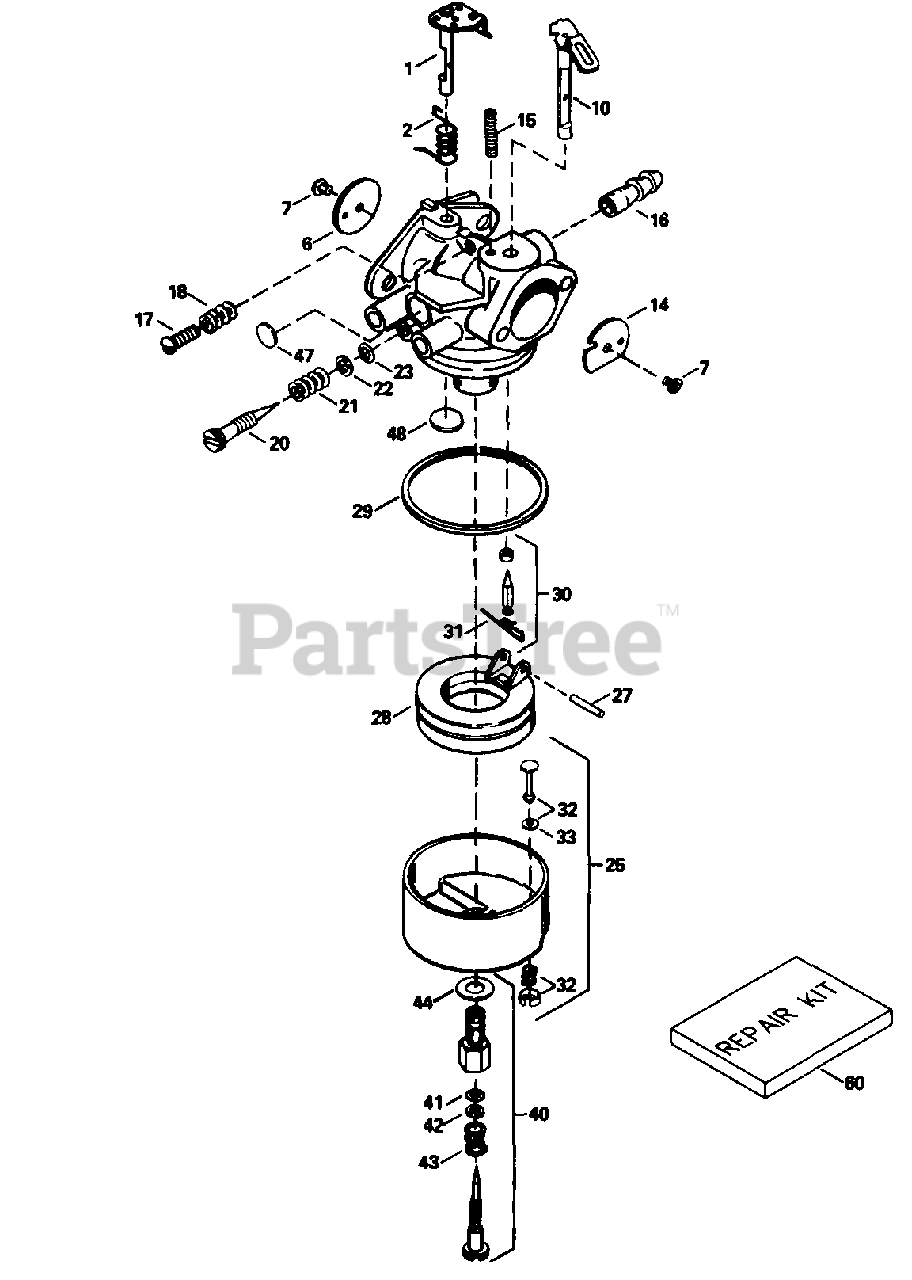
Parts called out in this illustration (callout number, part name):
1	Throttle Shaft and Lever Ass'y.
2	Throttle Return Spring
6	Throttle Shutter
7	Throttle & Choke Shutter Screw
10	Choke Shaft & Lever Ass'y
14	Choke Shutter
15	Choke Positioning Spring
16	Fuel Fitting
17	Idle Speed Screw
18	Tension Spring
20	Idle Mixture Screw
21	Spring, Idle Mixture Screw
22	Washer, Idle Screw
23	"O"-Ring, Idle Screw
25	Float Bowl
27	Shaft, Float
28	Float
29	"O"-Ring, Float Bowl to Body
30	Inlet Needle, Seat & Spring Clip
31	Spring Clip
32	Bowl Drain Ass'y.
33	Drain Plunger Gasket
40	High Speed Mixture Screw Ass'y
41	"O"-Ring, High Speed Mixture Screw
42	Washer, High Speed Mixture Screw
43	Tension Spring, High Speed Mixture Screw
44	Bowl Nut Washer
47	Welch Plug, Idle Mixing Well
48	Welch Plug, Atmospheric Vent
60	Repair Kit
